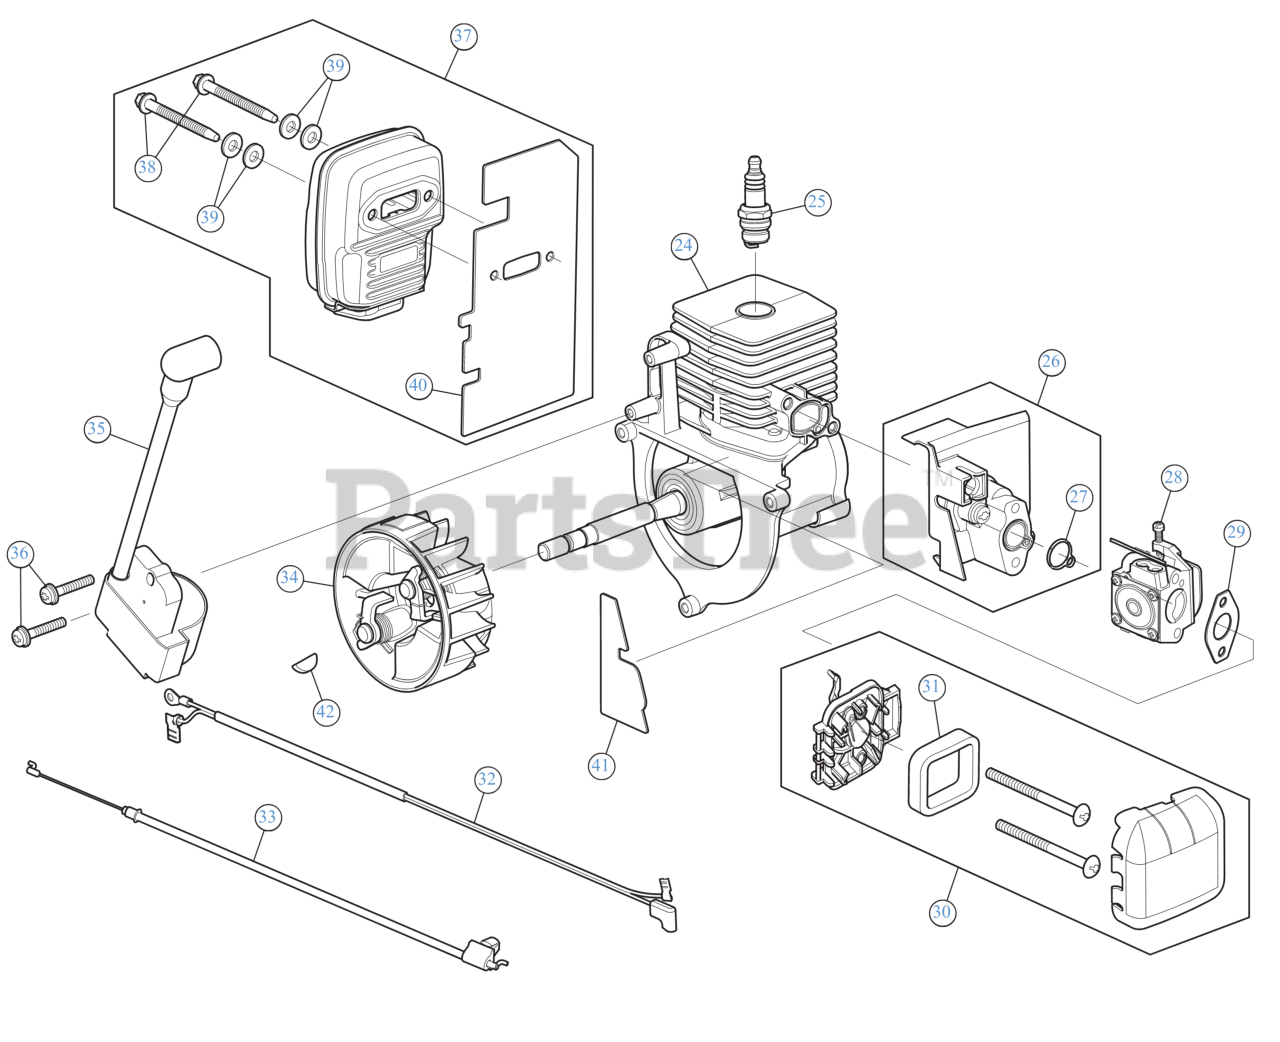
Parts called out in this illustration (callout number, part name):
24	SHORT BLOCK
25	SPARK PLUG
26	INTAKE ASSEMBLY
27	O-RING
28	CARBURETOR
29	GASKET CARB
30	AIR CLEANER ASSEMBLY
31	AIR FILTER
32	WIRE LEAD
33	THROTTLE CABLE
34	FLYWHEEL ASSEMBLY
35	MODULE
36	SCREW 8-32X.750
37	MUFFLER ASSEMBLY
38	MUFFLER SCREW
39	WASH, FLAT .480X.1
40	GASKET
41	SHORTBLOCK GASKET
42	WOODRUFF KEY #403-.125 x .375
